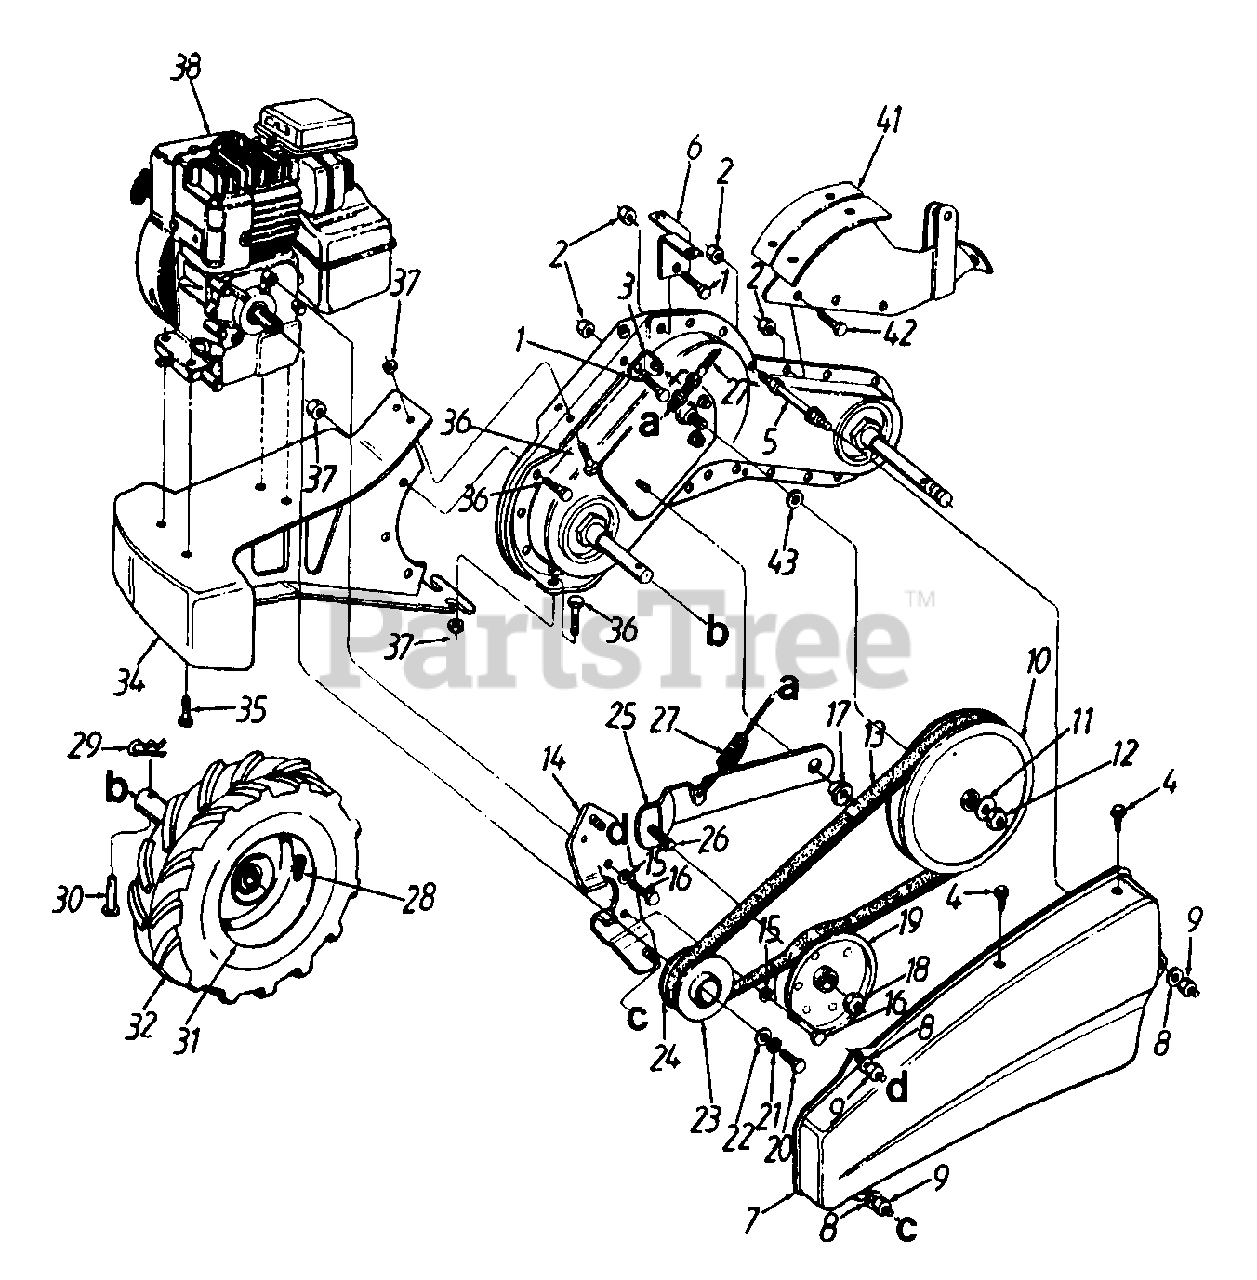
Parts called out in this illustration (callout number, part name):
1	Hex Bolt 5/16-18 x .75" Lg.
2	Hex Top L-Nut 5/16-18 Thd.
3	Cable Mtg. Bracket
4	Torx Mach. AB-Tap Scr. 1/4 x .6" Lg
5	Belt Cover Bolt
9	Hex Cap Nut 1/4-28 Thd.
10	Flat Pulley 8" O.D.
11	Bell-Wash. .38" I.D. x .88" O.D.
12	Hex Flange Nut.
13	"V"-Belt
16	Hex Bolt 5/16-24 x .62" Lg.
17	Shld. Nut
18	Hex Jam L-Nut 3/8-16 Thd.
19	Fl-Idler w/Flanges
20	Hex Bolt 3/8-24 x 1" Lg.
21	L-Wash. 3/8" I.D.
22	Fl-Wash. 3/8" I.D. x 1" O.D.
23	Outer Engine Pulley Half
24	Inner Engine Pulley Half
26	Hex Bolt 3/8-16 x 1.25" Lg.
27	Clutch Cable
28	Air Valve
29	Hairpin Clip
30	Clevis Pin
34	Frame Counterweight
35	Hex TT-Tap Scr. 3/8-16 Thd.
36	Hex Bolt 5/16-18 x 1" Lg. (Gr. 5)
37	Hex Flange L-Nut 5/16-18 Thd.
38	Engine
43	Wash. Fl. .635 I.D. x .930 O.D. x .03
